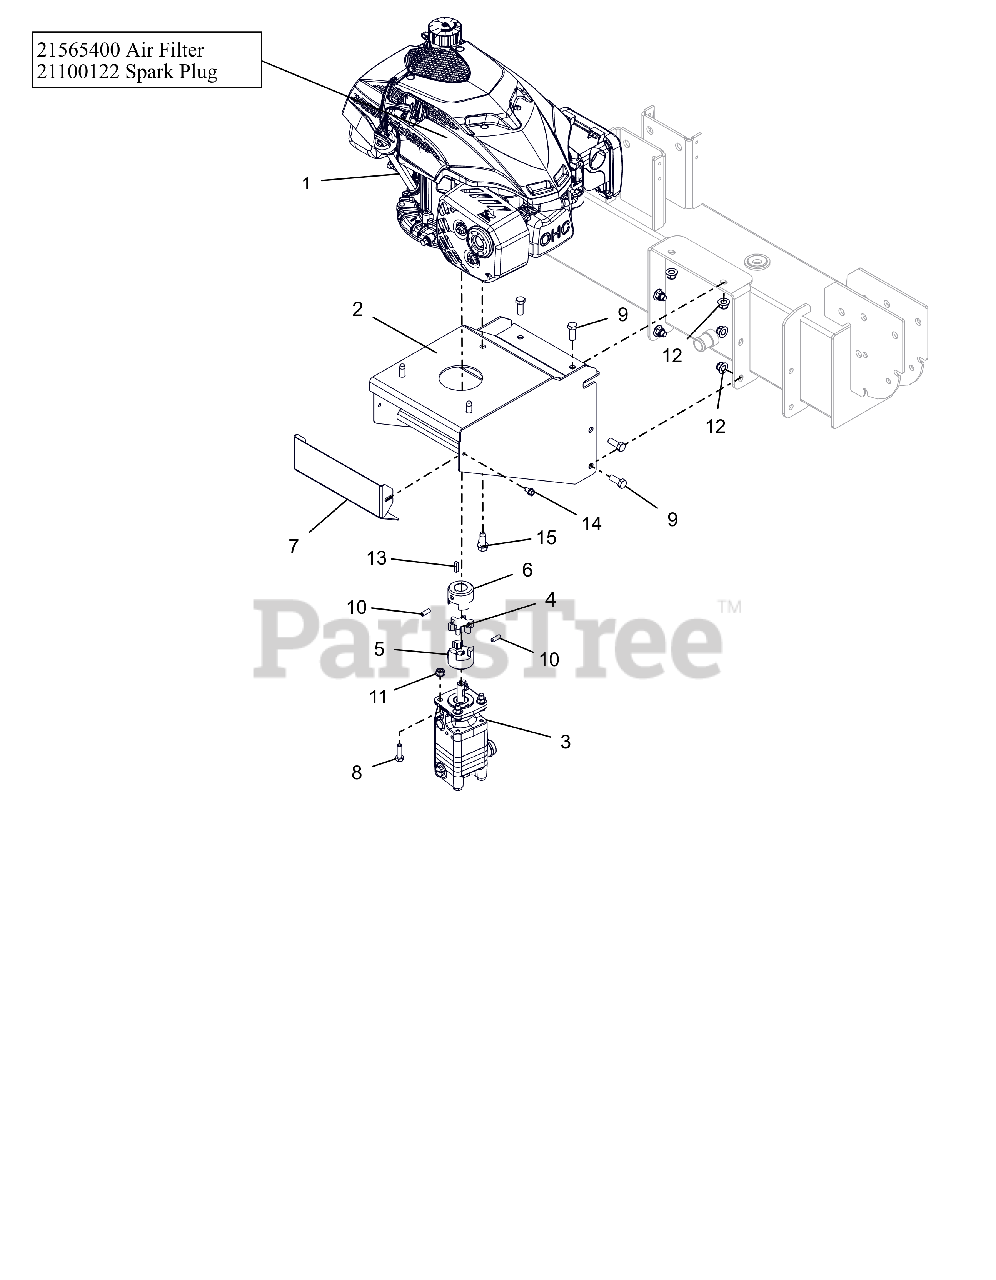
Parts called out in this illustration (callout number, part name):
1	ENGINE, YAMAHA MA190 (CARB)
1	FILTER, AIR
1	PLUG, SPARK
2	ENGINE MOUNT W/SAFTY DECAL-27T
3	PUMP,SPLITTER-11 GPM
4	SPIDER - URETHANE
5	COUPLER - DRIVE 1/2"
6	COUPLER - DRIVE, 7/8"
7	COVER-COUPLER
8	@BLT-HEX .31-18X1.00 GR5 YWZC
9	@BLT-HEX .38-16X1.00 GR5 YWZC
10	SCR,SET .25-20X.75 PCPT SH
11	@NUT-LK-TOP-FLG .31-18 YWZC
12	@NUT-LK-NYL-FLG .38-16 YWZC
13	KEY-SQ .188X.75X.188
14	SCR-TAP .25-20X.50 HWH TR YWZ
15	@SCR-TAP .38-16X1.00 HWH TR YZ
